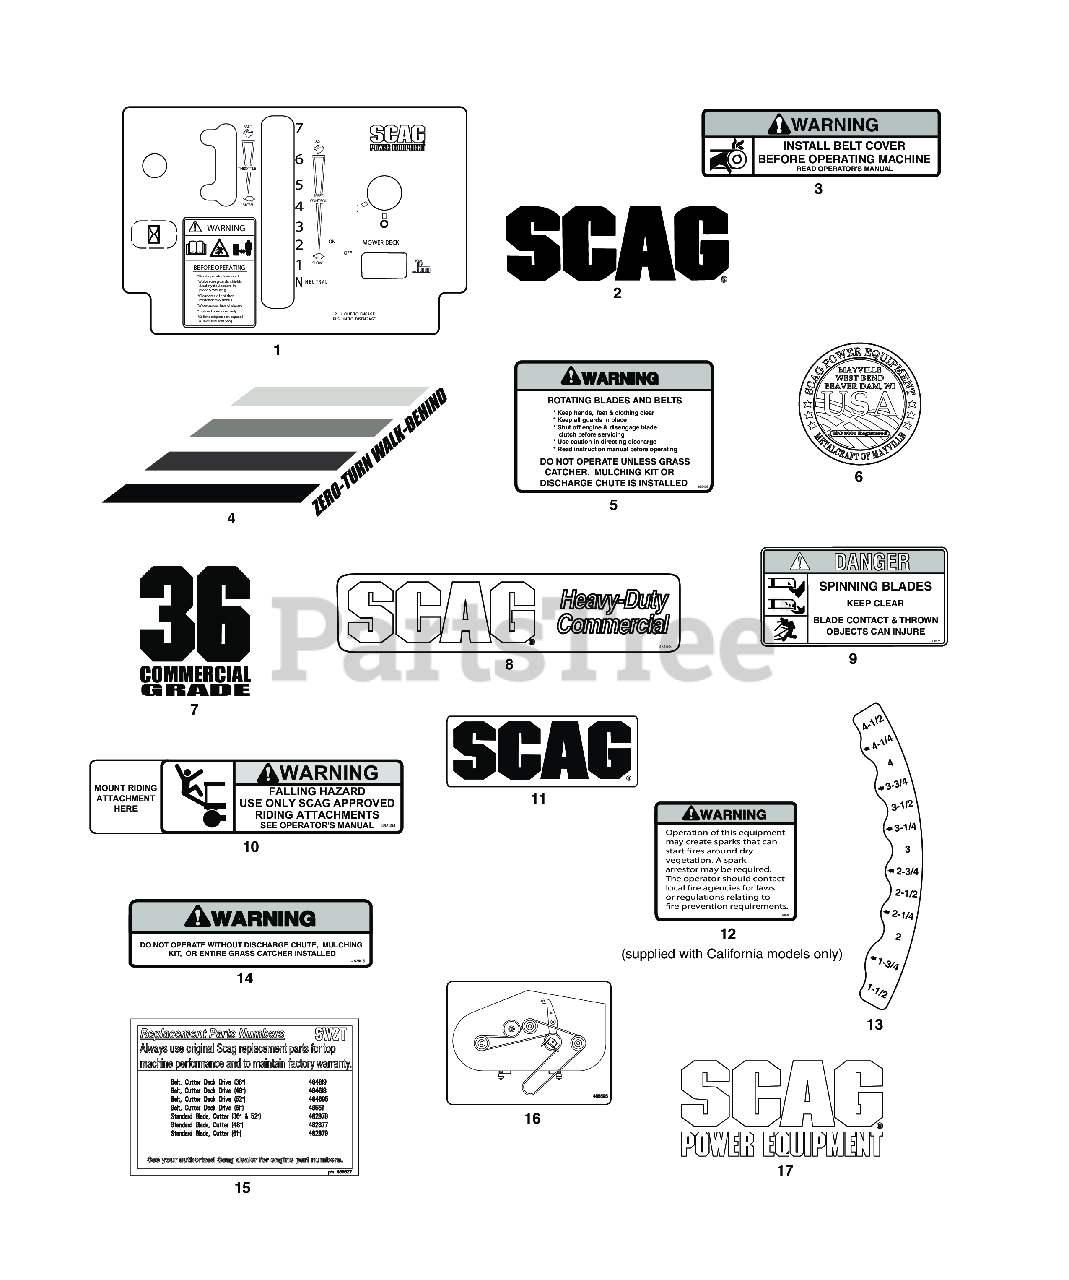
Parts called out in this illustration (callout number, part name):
1	Decal, Instrument Panel (Manual Start)
2	Decal, Scag Logo ( Cutter Deck)
3	Decal, Warning - Belt Cover
4	Decal, Handle - LH
5	Decal, Warning - Rotating Blades
6	Decal, Metalcraft - USA
7	Decal, 52 Commercial
8	Decal, Scag Heavy Duty Commercial
9	Decal, Spinning Blades
10	Decal, Sulky Attachment
11	Decal, Scag Logo
13	Decal, Height of Cut
14	Decal, Warning-Discharge
15	Decal, SWZT Replacement Parts
16	Decal, Belt Routing
17	Decal, Scag Power Equipment (Fuel Tank)
